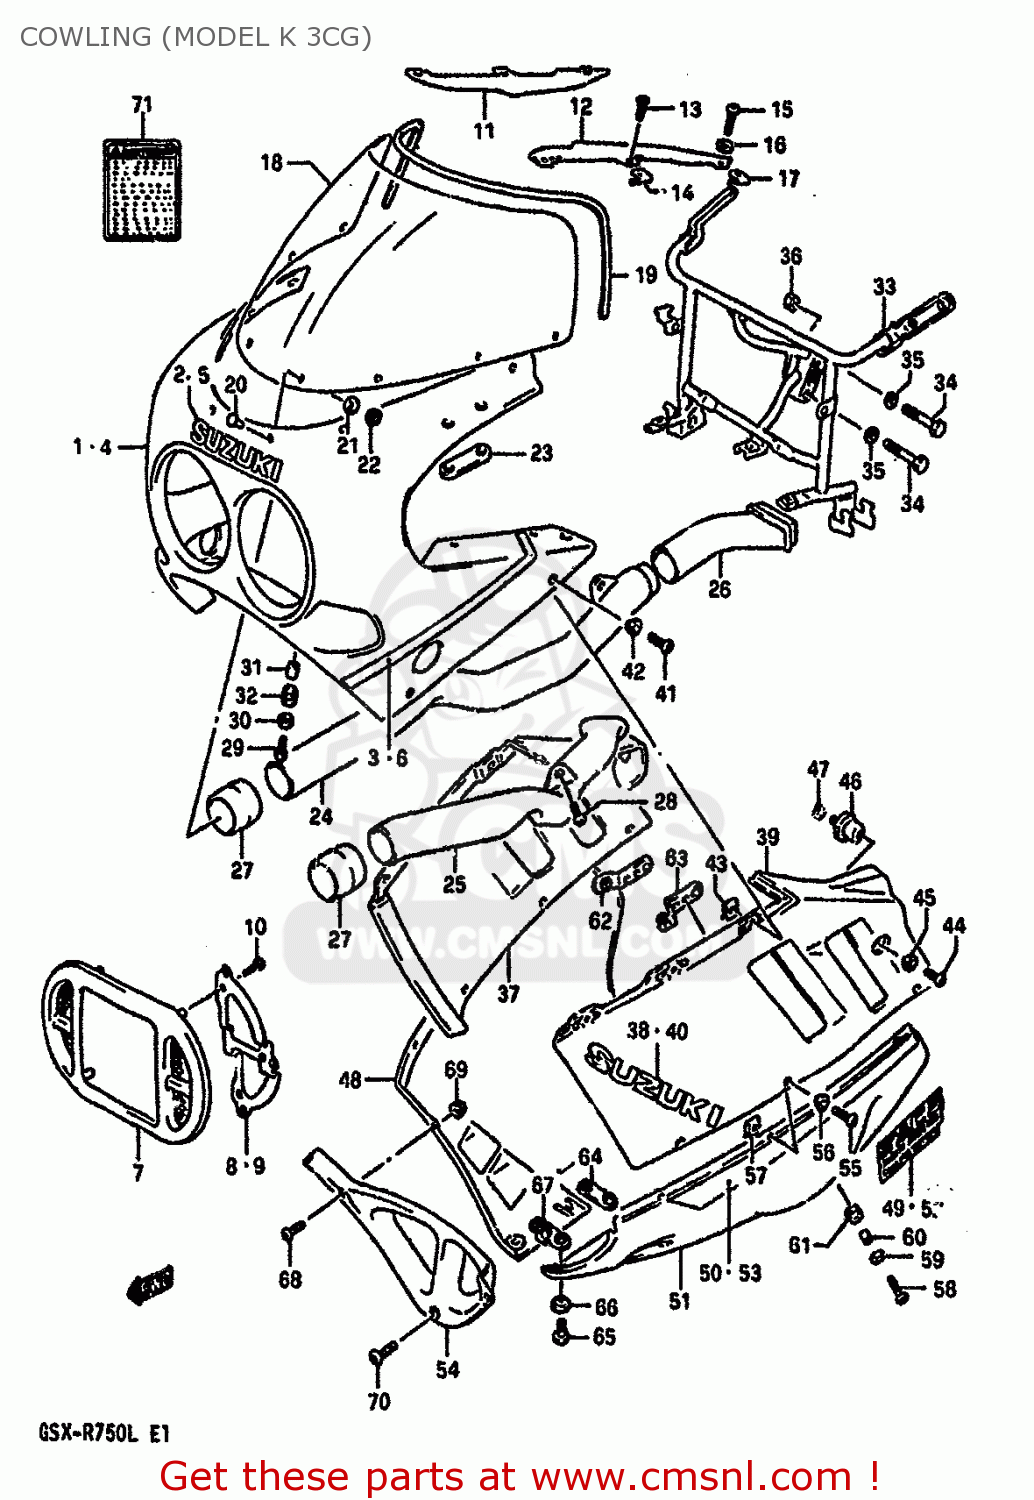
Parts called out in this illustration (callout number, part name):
1	BODY ASSY,COWLIN (BLACK/GRAY)
2	EMBLEM,COWLING FR
3	TAPE SET
4	BODY ASSY,COWLING (BLACK/GRAY)
5	EMBLEM,COWLING FR
6	TAPE SET
7	COVER,FRONT (BLACK)
8	PLATE,COVER RH
9	PLATE,COVER LH
10	TAPPING SCREW 4X10/A
11	PANEL,COWLING UPPER,RIGHT
12	COVER,COWLING,LEFT
13	SCREW(5X10)
14	NUT
15	SCREW(5X14)
16	WASHER(5.2X11X1)
17	NUT
18	WINDSCREEN
19	MOLDING
20	PIN,WINDSCREEN
21	CUSHION
22	NUT
23	CUSHION,RR VIEW MIRRORR
24	PIPE,AIR INTAKE,FRONT
25	PIPE,AIR INTAKE,FRONT
26	PIPE,AIR INTAKE RR,R
27	JOINT,AIR INTAKE
28	SCREW
29	SCREW(6X20)
30	WASHER(6.5X18X1)
31	SPACER
32	CUSHION
33	BRACE,COWLING
34	BOLT
35	WASHER,LOCK,8.
36	NUT ,8MM
37	COVER,SIDE RH (BLACK/GRAY)
38	EMBLEM,COWLING SIDE
39	COVER,SIDE LH (BLACK/GRAY)
40	EMBLEM,COWLING SIDE
41	SCREW(5X18)
42	WASHER(5.2X14X1.5)
43	NUT,HEADLAMP HOUSING,UPPER
44	SCREW(6X12)
45	WASHER(6.3X16X1.5)
46	CUSHION,COWLING
47	WASHER,LOCK
48	COWLING,UNDER RH (BLACK/SILVER)
49	EMBLEM
50	TAPE,RH
51	COWLING,UNDER LH (BLACK/SILVER)
52	EMBLEM
53	TAPE,LH
54	COWLING,UNDER,CENTER
55	SCREW(5X18)
56	WASHER(5.2X14X1.5)
57	NUT,HEADLAMP HOUSING,UPPER
58	SCREW(6X20)
59	WASHER(6.5X18X1)
60	SPACER
61	CUSHION
62	BRACKET
63	BRACE,COWLING UNDER,LH
64	BRACE,COWLING LWR COVER RR
65	SCREW(6X16)
66	WASHER(6.3X16X1.5)
67	BRACE,COWLING LWR COVER
68	SCREW(5X14)
69	NUT
70	SCREW(6X16)
71	LABEL (WARNING SCREEN)
